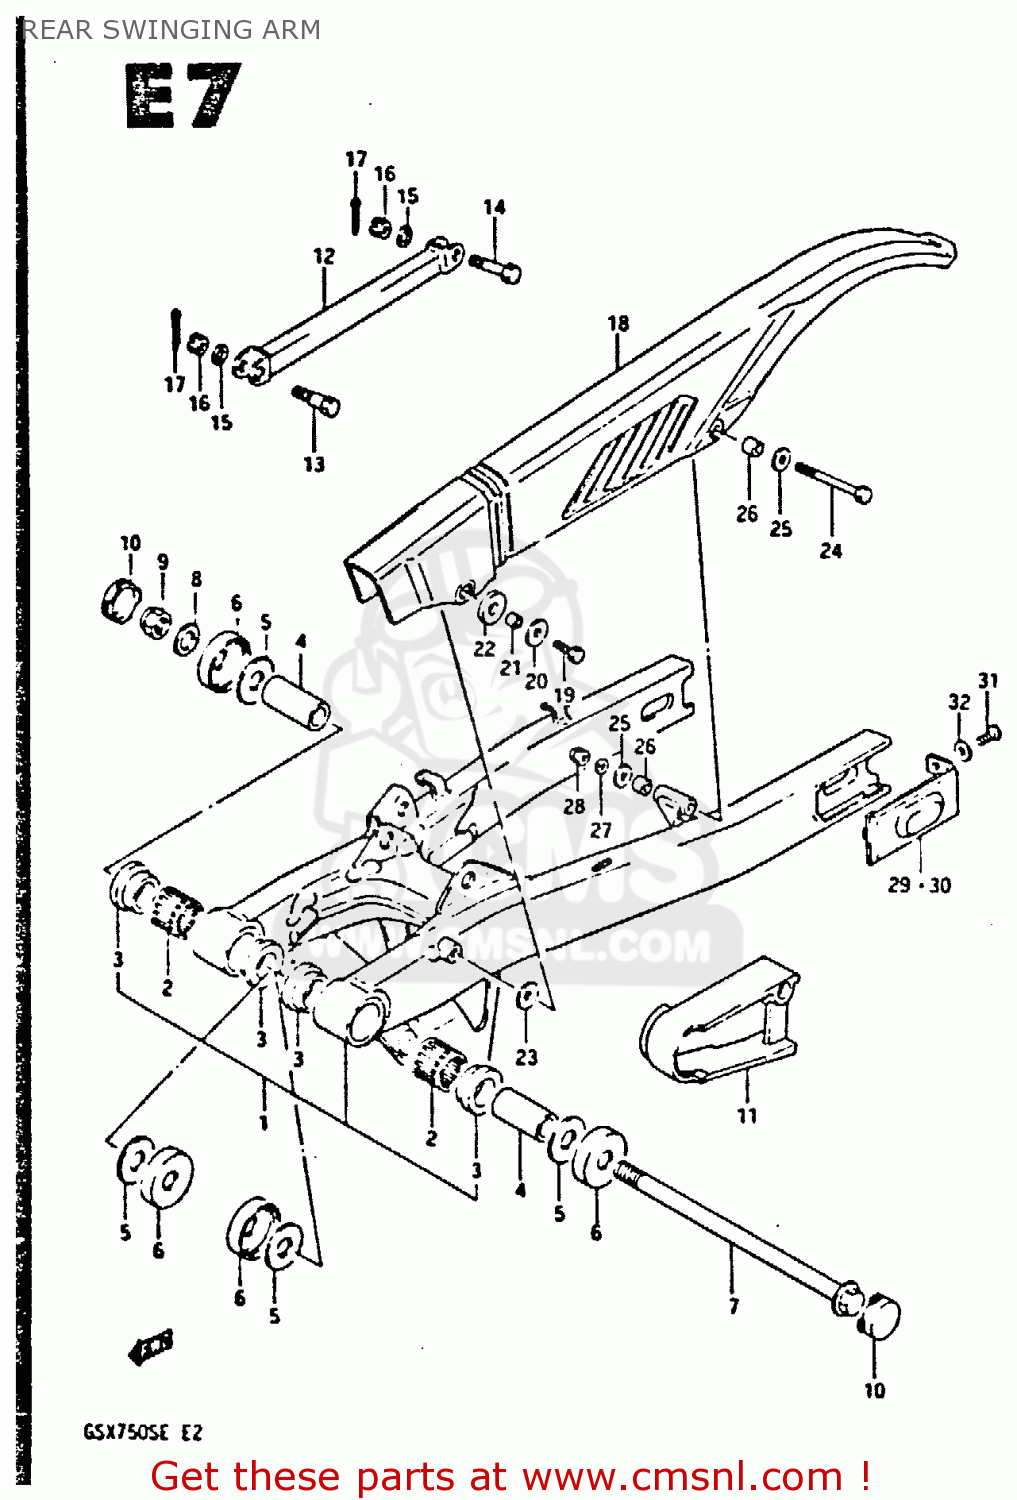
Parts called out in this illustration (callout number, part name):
1	SWINGING ARM SET (GOLD)
2	BEARING(25X33X30)
3	BUSHING
4	SPACER,RR SWGARM PIVOT
5	WASHER
6	COVER,RR SWINGINGARM PIVOT
7	SHAFT,REAR SWING ARM
8	WASHER
9	NUT
10	CAP,PIVOT
11	BUFFER,DEFENSE
12	TORQUE LINK,REAR
13	BOLT
14	BOLT(10X39)
15	WASHER
16	NUT
17	PIN 20X20
18	CASE,CHAIN
19	BOLT 6X16
20	WASHER (6.5X22X1.6)
21	SPACER
22	WASHER
23	WASHER (6.5X22X1.6)
24	BOLT 6X60
25	WASHER(6.5X18X1)
26	SPACER
27	WASHER,LOCK
28	NUT 6MM
29	COVER, RH
30	COVER, LH
31	SCREW
32	WASHER
